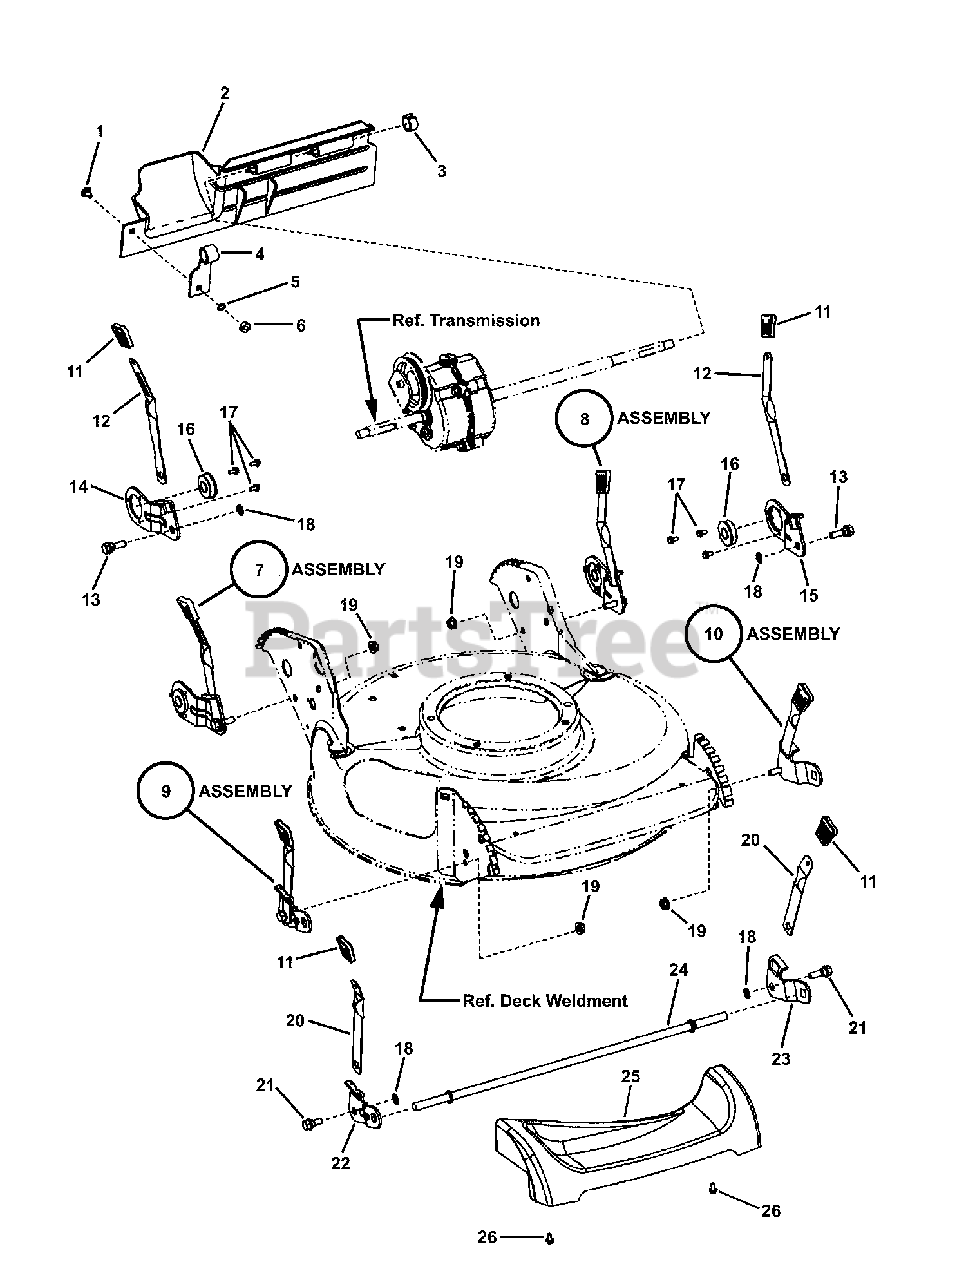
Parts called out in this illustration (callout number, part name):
1	BOLT, 1/4-20 x 1/2" Short Neck Carriage GR 5
2	FOOT GUARD, Rear
3	RING, Split (Black)
4	SUPPORT, Foot Guard
5	WASHER, 1/4" Internal Tooth Lock
6	NUT, 1/4-20 Hex, GR 5 or B
7	ASSEMBLY, Wheel Arm, Right Rear (S.P.)
8	ASSEMBLY, Wheel Arm Left Rear Long SP21S
9	ASSEMBLY, Front Right Wheel Arm
10	ASSEMBLY, Left Wheel Arm (.512" Square Hole)
10	ASSEMBLY, Front Left Wheel Arm (.453" Square Hole)
11	GRIP, Height Latch - Black (1.3" Wide)
12	LATCH, Height Adjusting (long)
13	BOLT, 5/16-18 x 1" Hex Washer Face Shoulder
14	ARM, Wheel, Right Rear
15	ARM, Wheel, Left Rear
16	BEARING, 9/16" I.D.
17	SCREW, #10-32 x 3/8" Hex Washer Self-Tap
18	RETAINER, 5/16" Bolt
19	NUT, 5/16-18 Hex Flange Lock, GR 5
20	LATCH, Height
21	BOLT, 5/16-18 x 3/4" Hex Washer Face Shoulder
22	WHEEL ARM, R.H. Front (Round Hole)
23	WHEEL ARM, L.H. Front (Square Hole)
24	AXLE, Front, Easy Line (3/8-16 Threads)
24	AXLE, 21 (7/16-20 threads, both ends)
25	COVER, Front 21" walk
26	SCREW, Round Washer Head Torx, Hi-Lo
